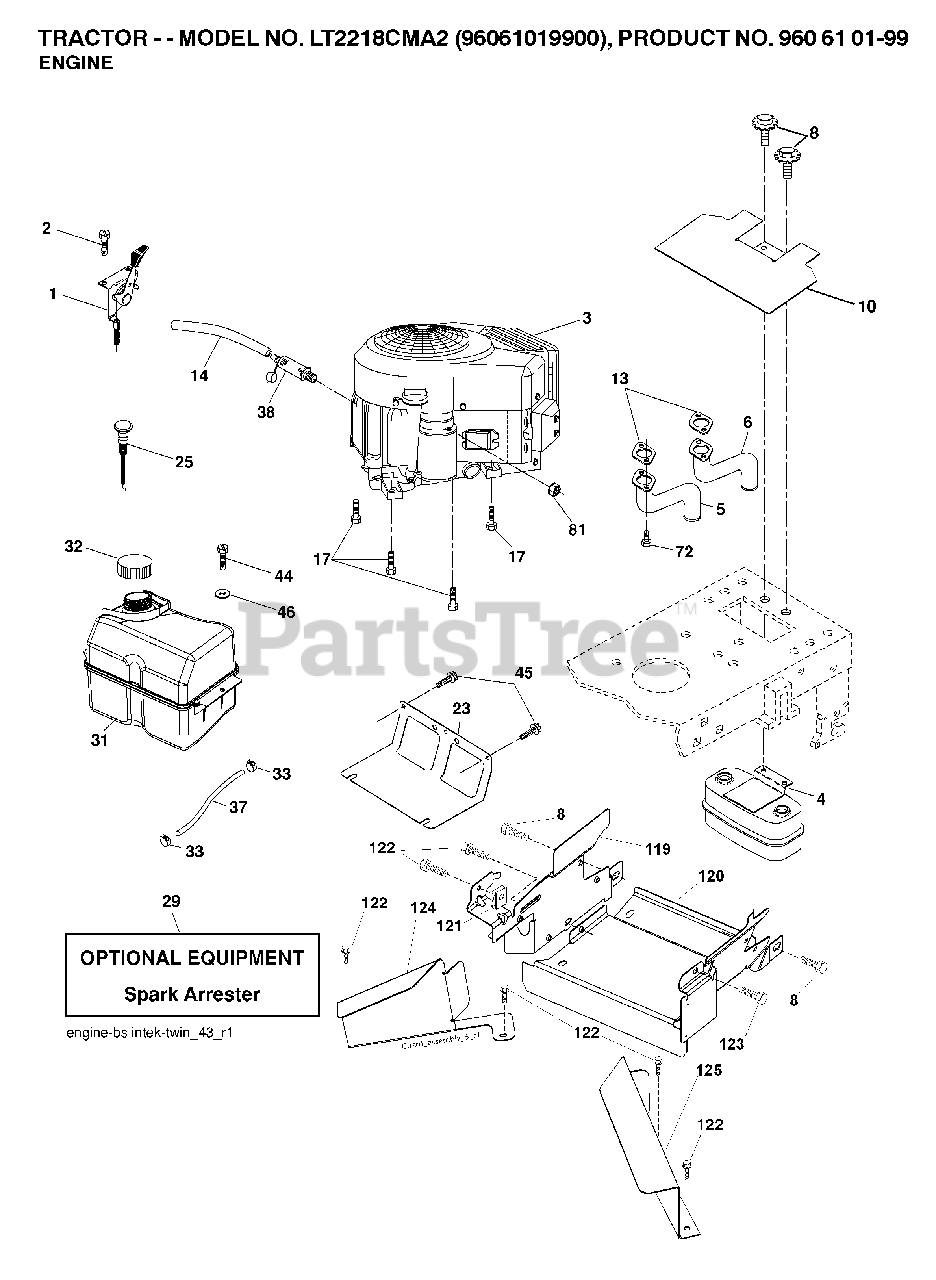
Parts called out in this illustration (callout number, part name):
1	THROTTLE CABLE
2	SCREW
4	MUFFLER.TWIN.CYL.LOW.TONE
5	EXHAUST TUBE RH
6	TUBE MANIFOLD LH
8	BOLT, 5/16-18 X 1 3/4
10	RP SHIELD HEAT MUFFLER
13	GASKET.MUFFLER
14	TUBE, DRAIN OIL ASM.
17	SCREW.3/8-16
23	SHEILD.BROWNING.DBR.GUARD
25	CONTROL CHOKE
29	ARRESTER SPARK (OPTIONAL)
31	FUEL TANK FRT 2 GAL.
32	FUEL CAP
33	HOSE CLAMP
37	LINE.FUEL.20
38	PLUG DRAIN OIL EASY
44	SCREW HEXWSHR 1/4-20X3/4
45	SCREW, 3/8-16X3/4
72	SCREW.SOCKET.HEAD.5/16-18
81	NUT
122	SCREW.1/4-20X5/8
123	SCREW, 5/16-18 X 1/2
